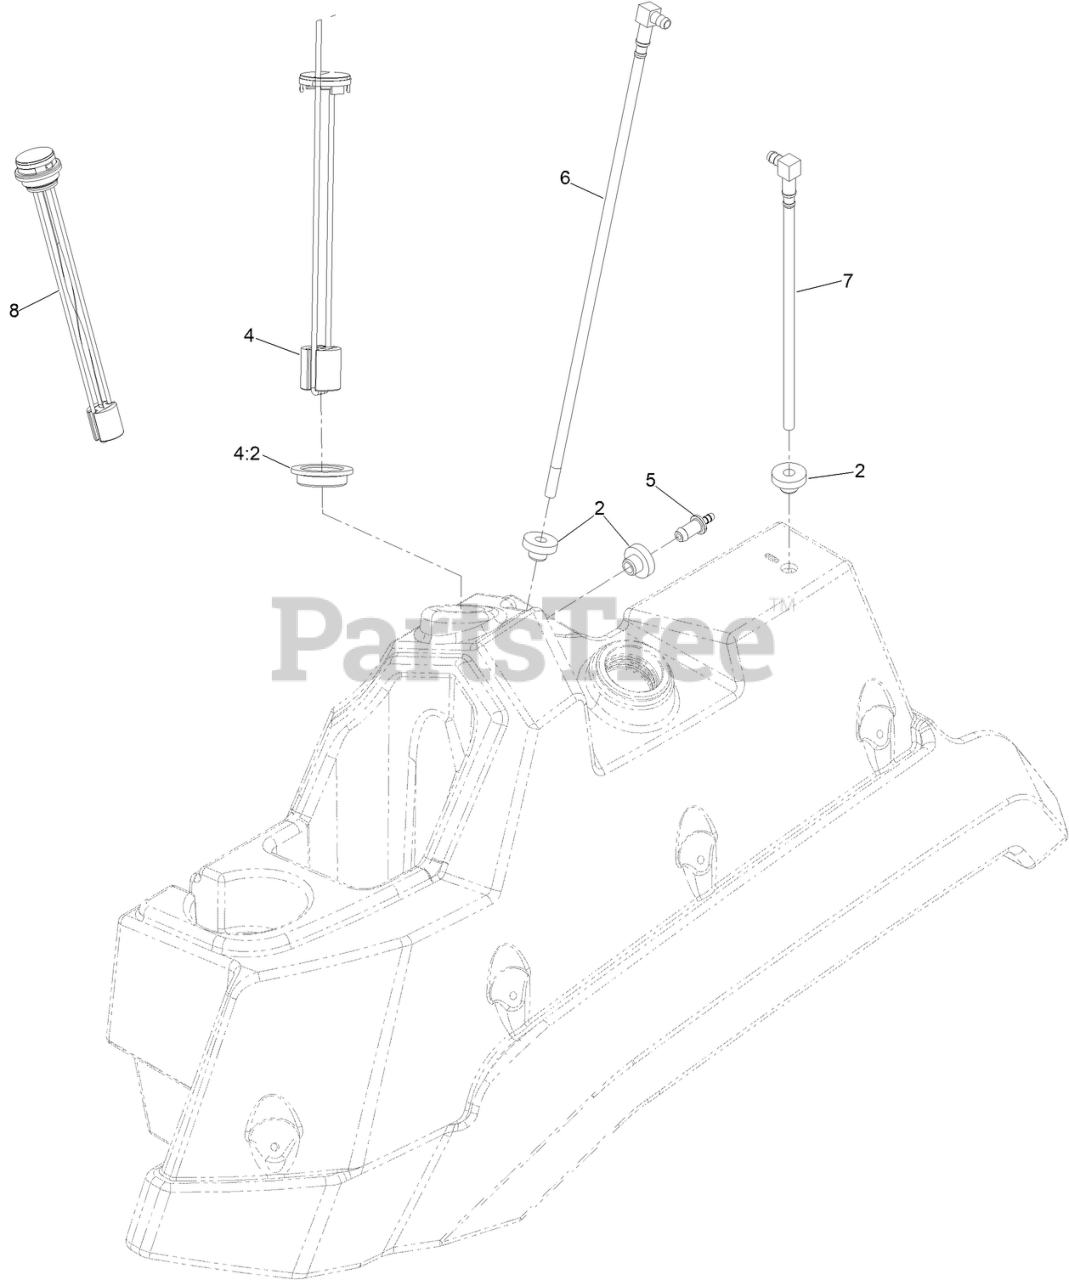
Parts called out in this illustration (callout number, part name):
2	BUSHING
4	GAUGE-FUEL
4:2	Seal-Fuel Gauge
5	FITTING-ORIFICE, STRAIGHT
6	PICK-UP-FUEL
7	RETURN-FUEL
8	GAUGE-FUEL
